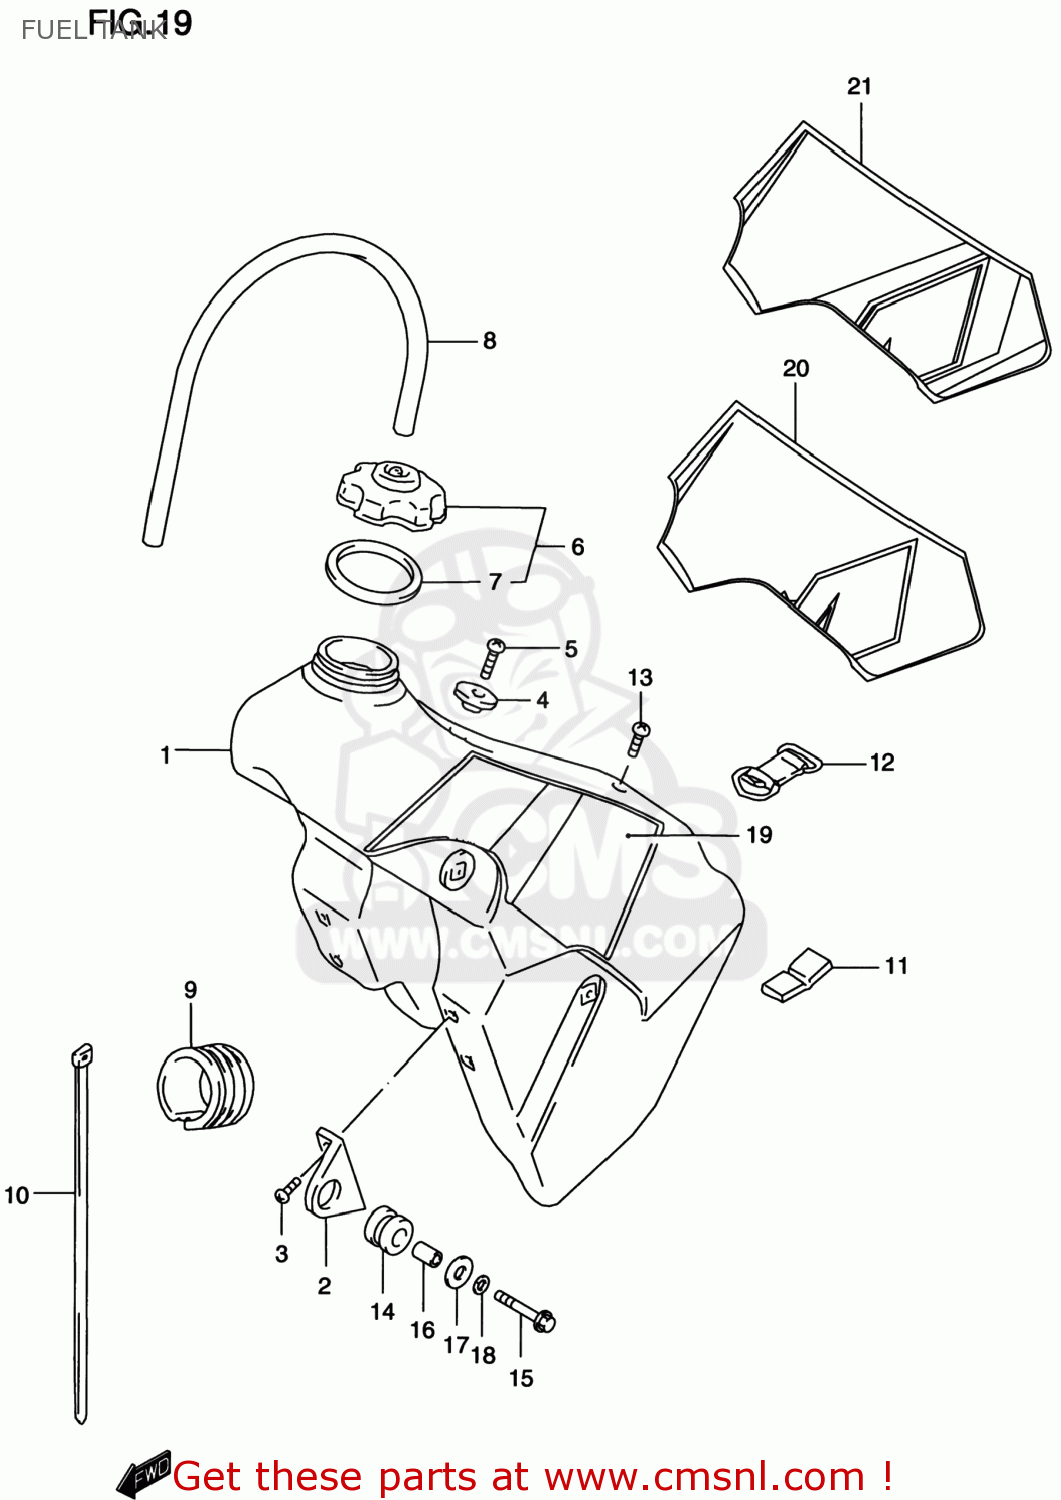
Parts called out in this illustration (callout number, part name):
1	TANK,FUEL(YELLOW)
2	BRACKET,FUEL TANK FR
3	SCREW
4	HOOK,SEAT FR
5	SCREW
6	CAP SET,FUEL TANK
7	GASKET,CAP (NAS)
8	HOSE (5.3X10.5X600)
9	CUSHION,FUEL TANK NO.1
10	CLAMP(L:300)
11	CUSHION
12	BAND,FUEL TANK RR
13	SCREW
14	CUSHION,MUFFLER
15	BOLT,G/S SWITC
16	SPACER(6.5X9X13.5)
17	WASHER(6.5X24X1.2)
18	LOCK WASHER
19	TAPE SET,FUEL TANK
20	TAPE SET,FUEL TANK
21	TAPE SET,FUEL TANK
